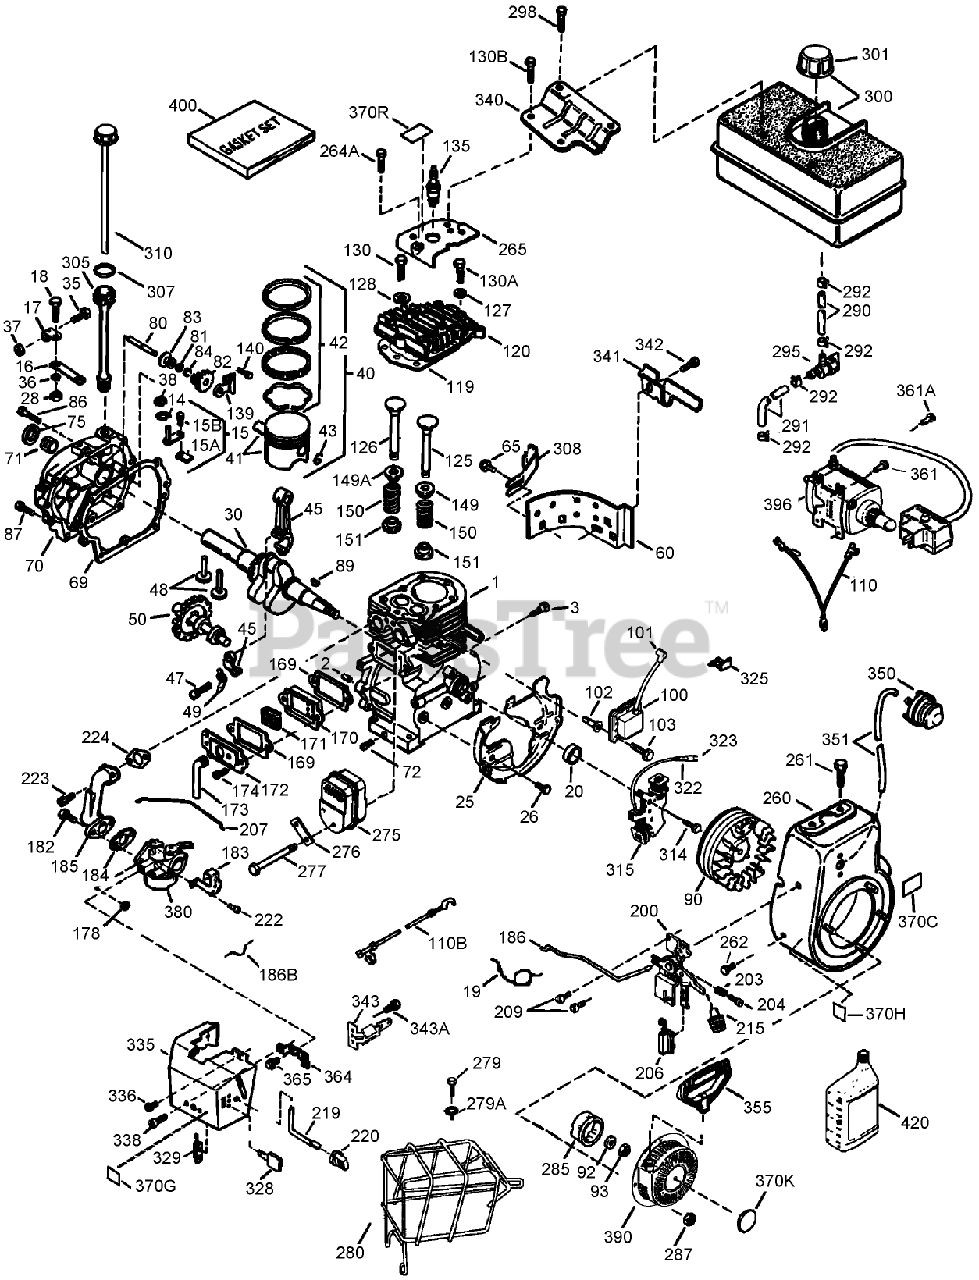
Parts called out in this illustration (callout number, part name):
209	Screw (10-32 x 1/2)
215	Knob-Control
219	Rod-Choke
220	Knob-Control
222	Screw (10-32 x 1/2)
223	Screw (T-30, 5/16-18x1-3/32)
224	Gasket-Pipe, Intake
260	Housing-Blower
261	Screw (5/16-18x3/4)
262	Screw (5/16-18x9/16)
264A	Screw (1/2-20x5/8)
265	Cover-Head, Cylinder (Black)
275	Muffler
276	62513 SNWTHWR W/284
277	Screw (5/16-18x4-3/16)
278	Washer-Flat
279	Screw (10-16 x 47/64)
279A	washer-Lock
280	Muffler Heat Shield ASM (Includes 278, 279, 279A)
285	Cup-Starter
287	Nut and Lock Washer (1/4-28)
290	Line-Fuel
291	Line-Fuel (8.62)
292	Clamp-Line, Fuel
295	Valve-Shut Off, Fuel
298	Screw (1/4-15x7/8)
300	Tank-Fuel (Includes 292, 301)
301	Cap-Fuel (Black) (1-1/2 I D)
305	Tube-Fill, Oil
307	O-Ring
308	Clip-Tube, Fill
310	Dipstick
314	Screw (1/4-20 x 3/4)
315	Coil-Alternator, 18 Watt (Includes 323)
322	Body-Connector
323	Terminal
325	Clip-Wire
328	Key-Ignition
329	Terminal
335	Cover-Carburetor (Black)
336	Screw (10-32x1/2)
338	Screw (10-32 x 3/8)
340	Bracket-Tank, Fuel (Black)
341	Bracket-Tank, Fuel
342	Screw (1/4-20x19/32)
343	Bracket-Switch, Key
343A	Screw (8-32 x 23/64)
350	Primer ASM
351	Line-Primer
355	Handle-Starter, Mitten Grip
361	Screw (T-30, 1/4-20x15/32)
361A	Screw
364	Bracket-Cover, Carburetor
365	Screw (8-32x27/64)
370C	Decal-Primer, International Symbol
370G	Decal-Instruction
370H	Decal-Speed Control and Choke
370K	Decal-Tecumseh Logo for Top of Recoil Starter
370R	Decal-Warning (Bilingual)
380	Carburetor ASM (Includes 184)
390	Starter-Rewind
396	Electric Starter Motor ASM (220 Volt)
400	Gasket Set
420	Oil-Engine, S A E 5W30
